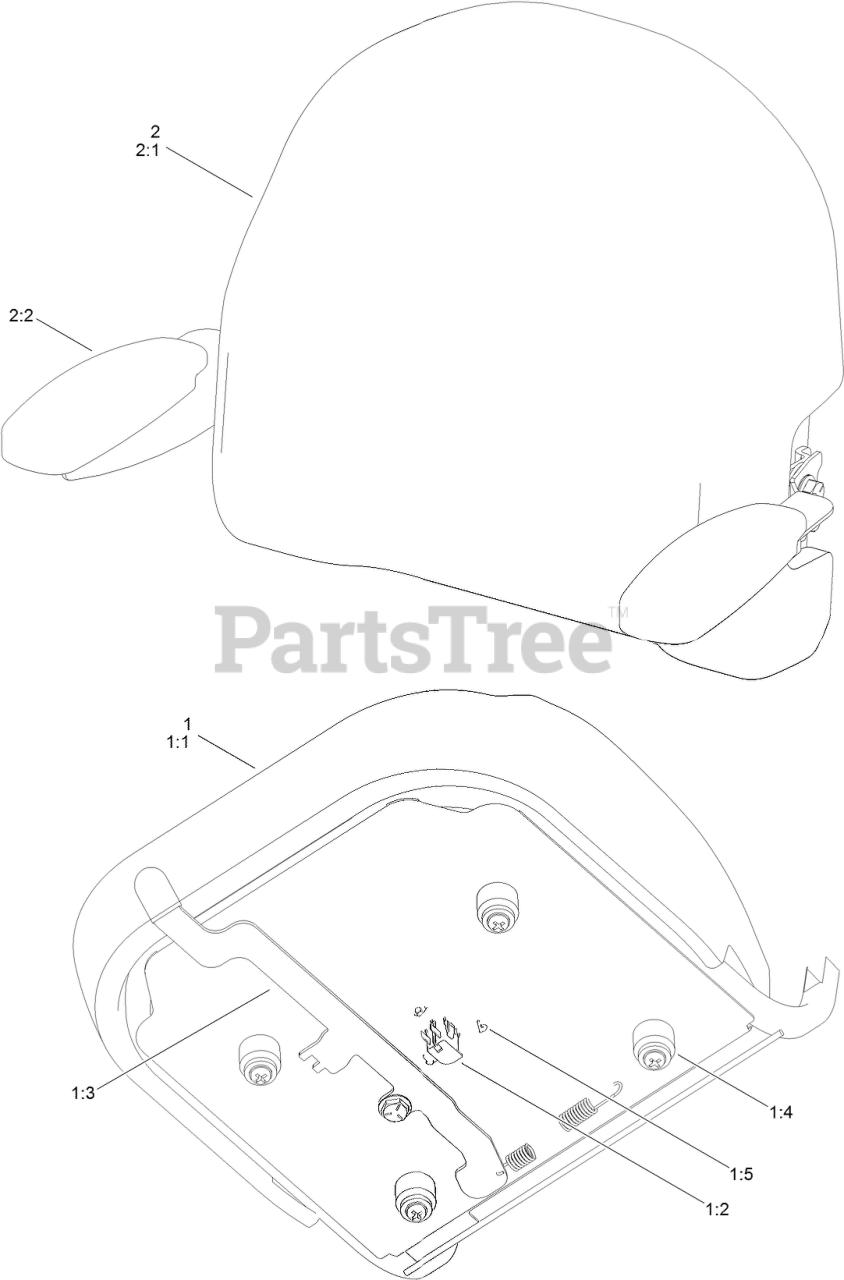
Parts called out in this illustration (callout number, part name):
1	SEAT ASM - BOTTOM
1:1	COVER-SEAT BASE
1:2	SWITCH-BAIL
1:3	TRACK ASM
1:4	BUSHING ASM
1:5	CAP-SWITCH, ACTUATOR
2	SEAT ASM -BACK
2:1	COVER-SEAT BACK
2:2	KIT-ARM REST
